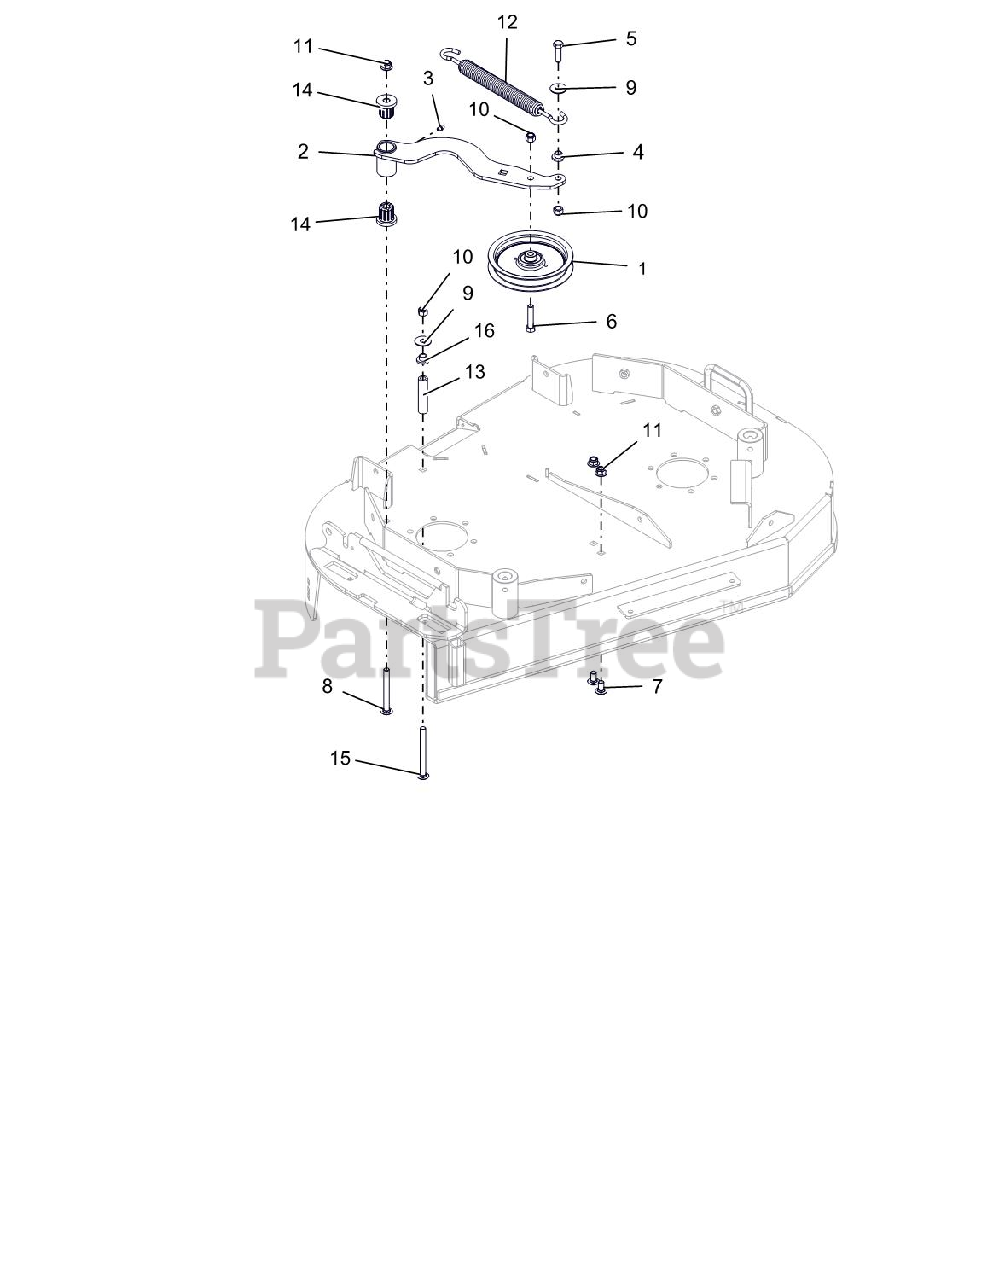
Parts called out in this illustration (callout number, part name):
1	IDLER, FLAT-5.00X.75
2	WLDMT, IDLER ARM
3	FTG-LUBE .25-28X.256 SST
4	BSHG-FLG .385X.500X.875X.406
5	BLT, HEX .38-16X1.25 G5 ZCC
6	BLT, HEX .38-16X1.75 G5ZC120
7	BLT-RHDSSQNK .38-16X.75 G5YZ
8	BLT-RHDSSQNK .38-16X3.50 G5YZ
9	WSHR-FL-STL .375X1.125X.065 ZC
10	NUT,NYL .38-16 G5 ZCC
11	NUT,LK-NYL-FLG .38-16 G5ZC120
12	SPRING, EXTENSION
13	TUBE, SPACER
14	BRG, FLG M10XM25XM27 FLUTED
15	BLT-RHDSSQNK .38-16X4.00 G5YZ
16	BSHG-FLG .385X.500X.875X.406
